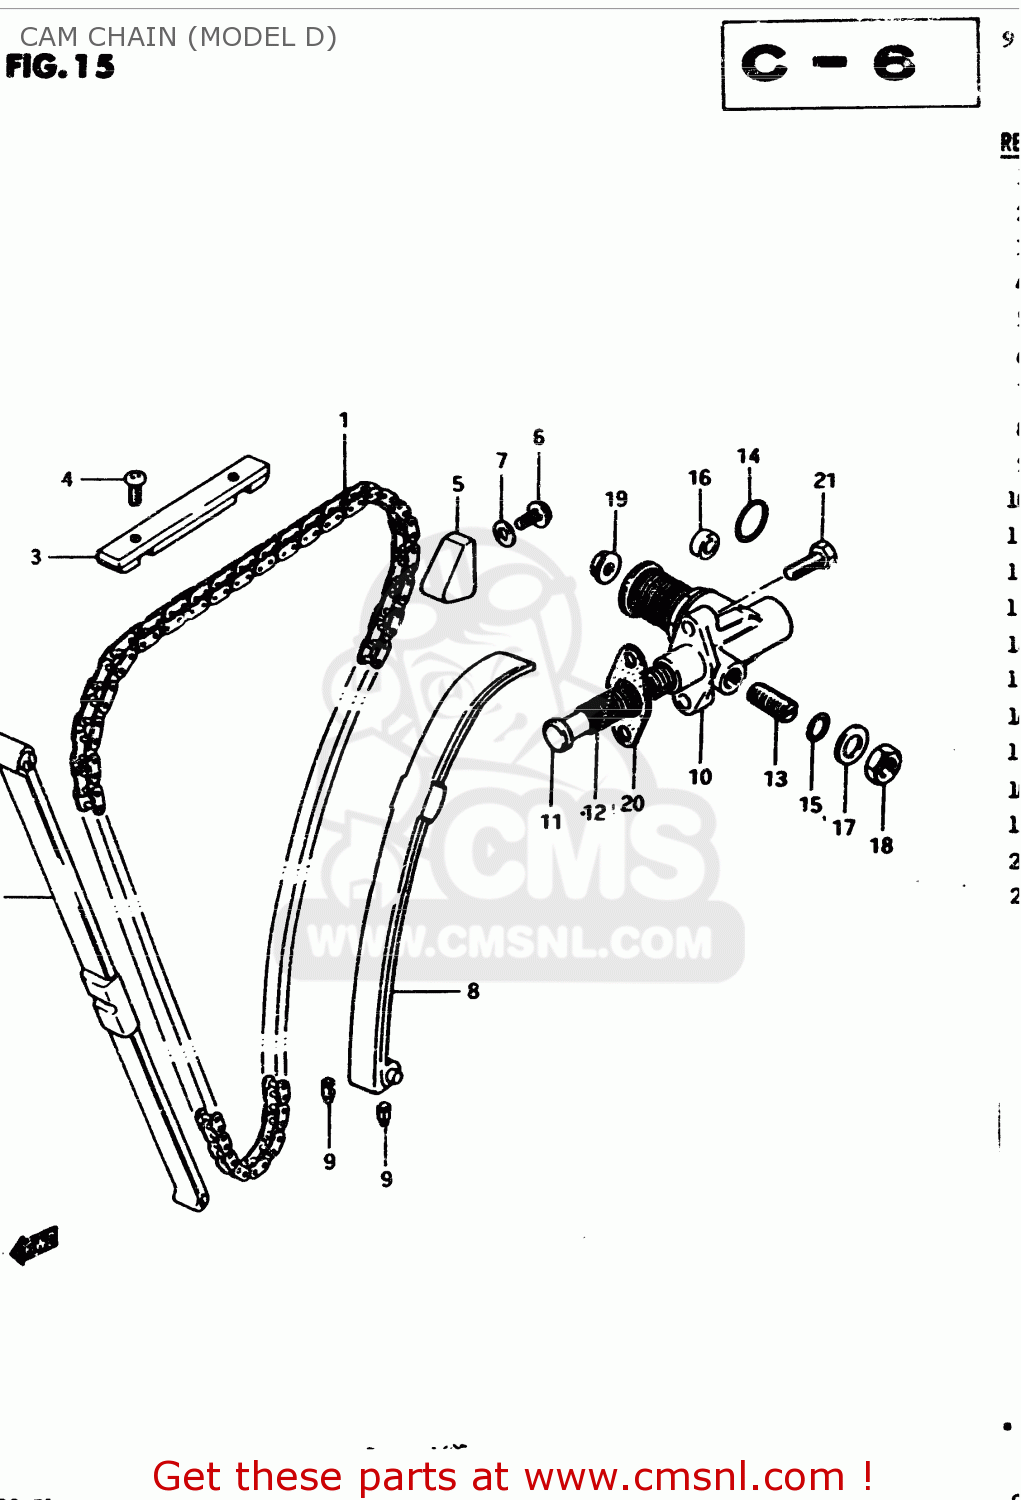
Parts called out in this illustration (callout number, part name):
1	CHAIN,CAMSHAFT DRIVE(120L)
2	GUIDE,CAM CHAIN NO.1
3	GUIDE,CAM CHAIN NO.3
4	SCREW
5	GUIDE,CAM CHAIN
6	BOLT 6X12
7	WASHER
8	TENSIONER,CAM CHAIN
9	CUSHION,CAM CHAIN TENSIONER
10	ADJUSTER ASSEMBLY,TENSIONER
11	ROD,PUSH
12	SPRING
13	SCREW,TENSIONER ADJUST
14	O RING(D:2.4,ID:20.8)
15	O RING(D:1.9,ID:5.7)
16	SEAL,OIL(10X16X4)
17	WASHER,8.5X16X
18	NUT
19	NUT 6MM
20	GASKET,TENSIONER ADJUSTER (MCA)
21	SCREW
